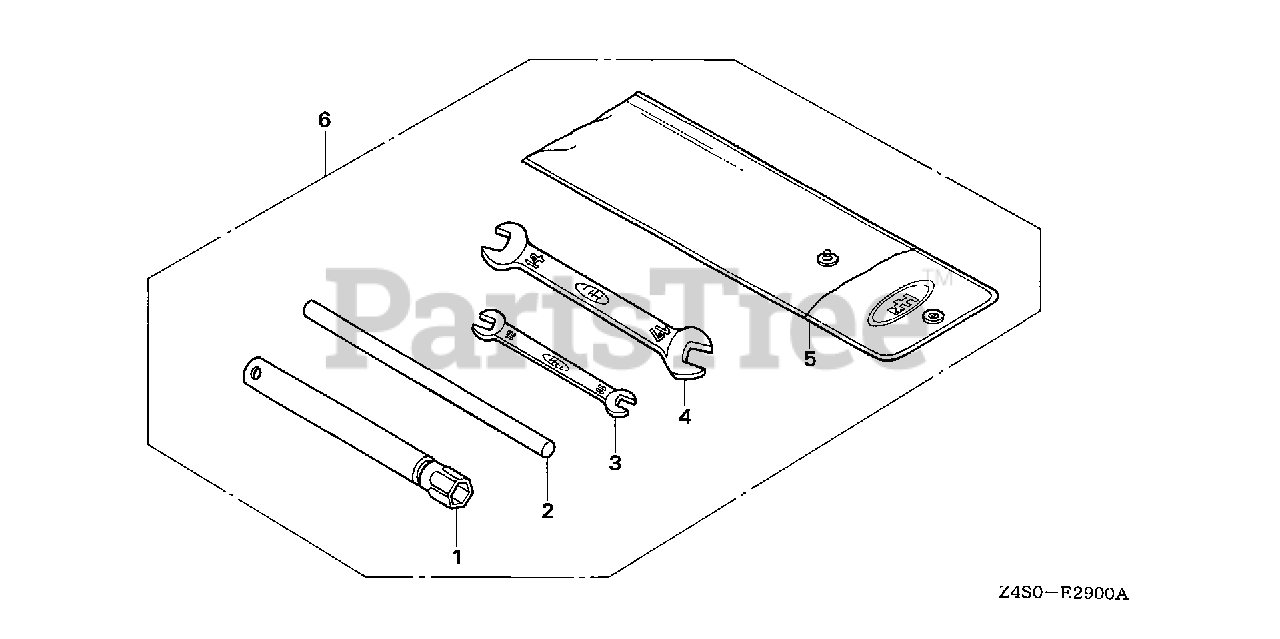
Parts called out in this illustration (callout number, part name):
1	WRENCH, SPARK PLUG
2	HANDLE, BOX WRENCH
3	SPANNER (10X12)
4	SPANNER (14X17)
5	BAG, TOOL (230MM)
